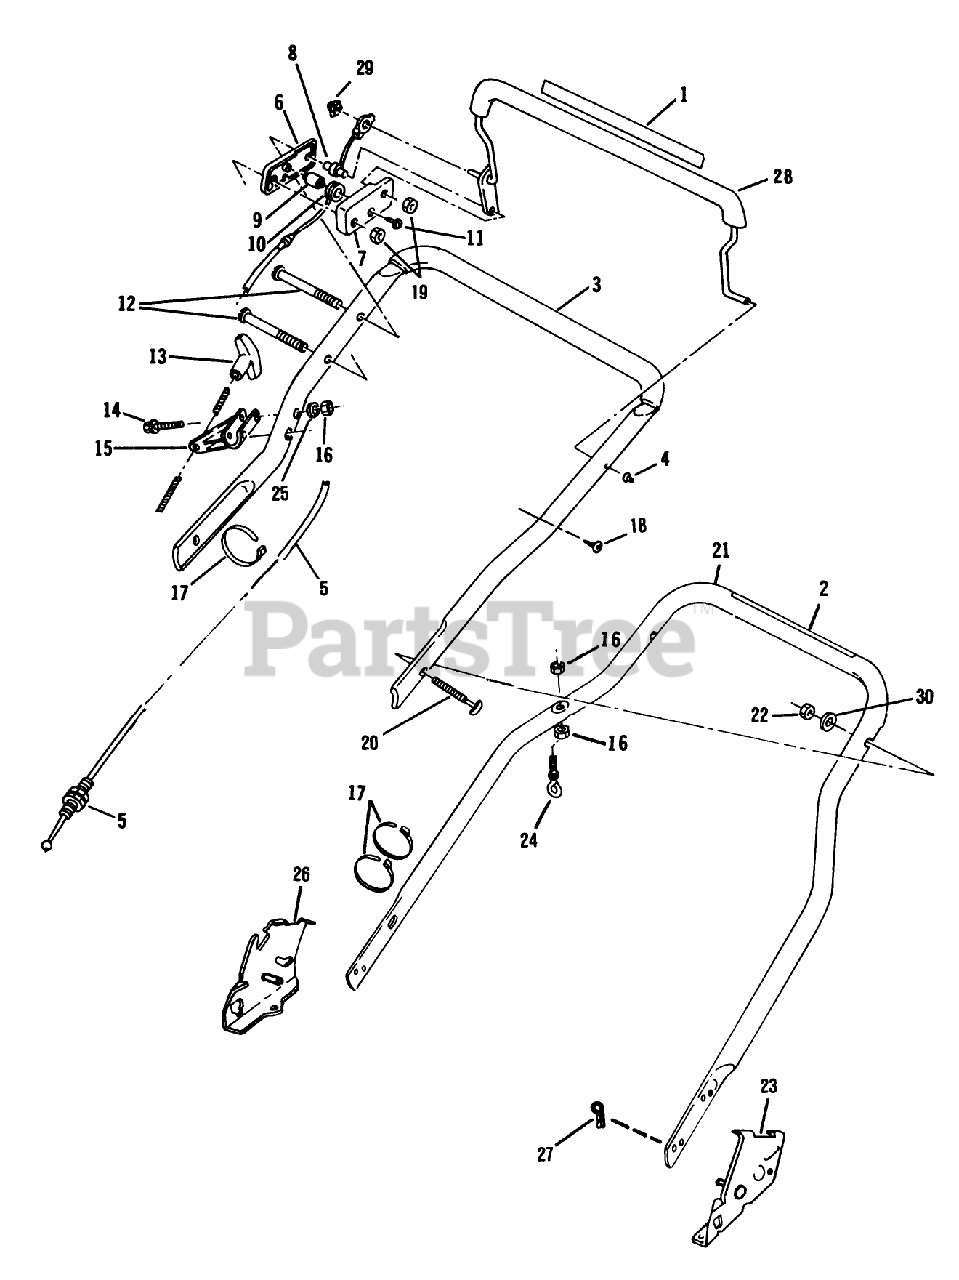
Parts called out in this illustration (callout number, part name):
5	CONTROL CABLE WES
8	COLUMN
9	PIN SKF
11	SCREW
13	HANDLE,STARTER
16	LOCKNUT E
18	SCREW LAWRENCE
19	NUT C/LOCK E
22	NUT-LOCK F
24	EYE BOLT WAS MFG
25	WASHER
27	HAIR PIN
29	NUT ACORN
30	WASHER-CURVED
